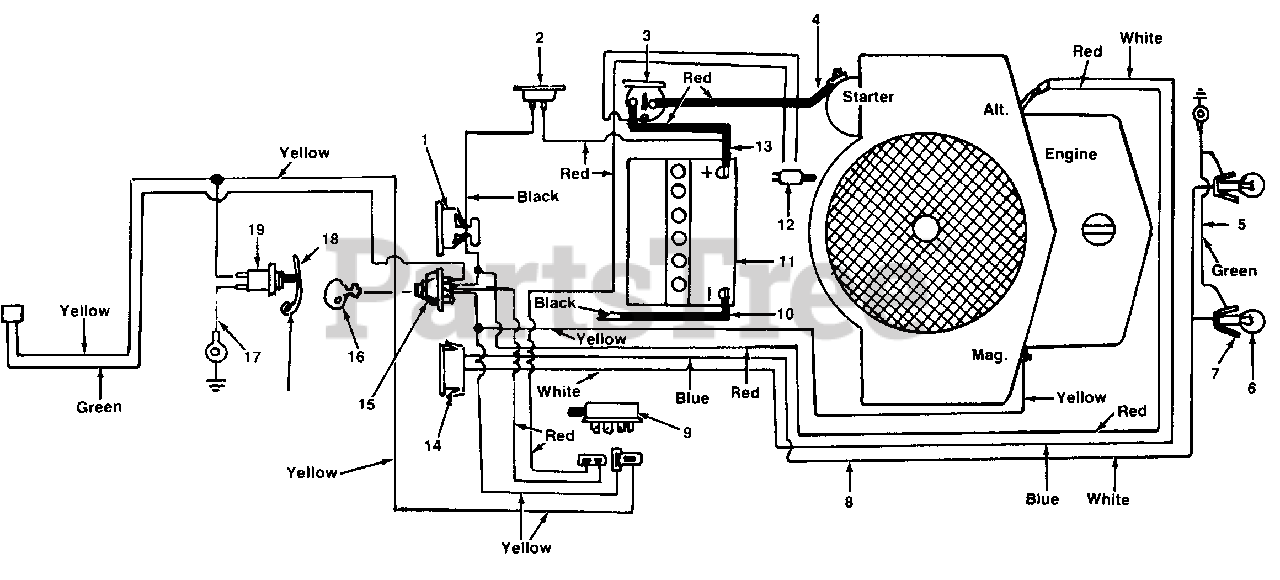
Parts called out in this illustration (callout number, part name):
1	Ammeter
2	Circuit Breaker
3	Solenoid
4	Wire
5	Ground Wire
6	Bulb
7	Socket
8	Wire Harness
9	Safety Switch
10	6 Ga. Black Wire
11	Battery 12V
12	Safety Switch
14	Light Switch
15	Ignition Switch
16	Ignition Key
17	Electric Wire
18	Spring Lever
19	Safety Switch
